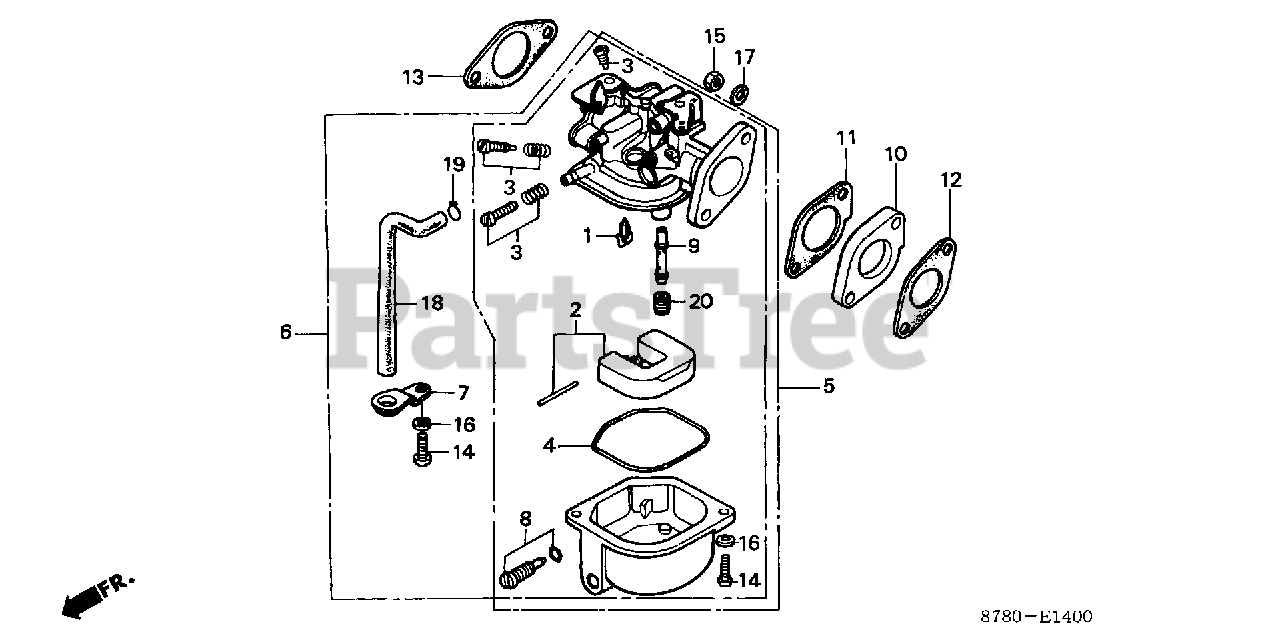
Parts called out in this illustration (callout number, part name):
1	VALVE SET, FLOAT (NOT AVAILABLE)
2	FLOAT SET (CARBURETOR NO.)
2	FLOAT SET (CARBURETOR NO.) (NOT AVAILABLE)
3	SCREW SET (CARBURETOR NO.)
4	O-RING (NOT AVAILABLE)
5	CARBURETOR ASSY. (BB01A A)
6	CARBURETOR ASSY. (BB04A C) (N/A: USE COMPONENT PARTS)
7	PLATE, STAY (CARBURETOR NO.)
8	SCREW, DRAIN (NOT AVAILABLE)
9	NOZZLE, MAIN (NOT AVAILABLE)
10	INSULATOR, CARBURETOR (NOT AVAILABLE)
11	GASKET A, CARBURETOR INSULATOR (NOT AVAILABLE)
12	GASKET B, CARBURETOR INSULATOR (NOT AVAILABLE)
13	GASKET, AIR CLEANER ELBOW (NOT AVAILABLE)
14	SCREW, PAN (4X12)
15	NUT, HEX. (6MM)
16	WASHER, SPRING (4MM)
17	WASHER, SPRING (6MM)
18	BULK HOSE, FUEL (3.5X3000) (3.5X120) (CARBURETOR NO.)
19	CLIP, TUBE (B7) (CARBURETOR NO.)
20	JET, AIR (#70) (NOT AVAILABLE)
